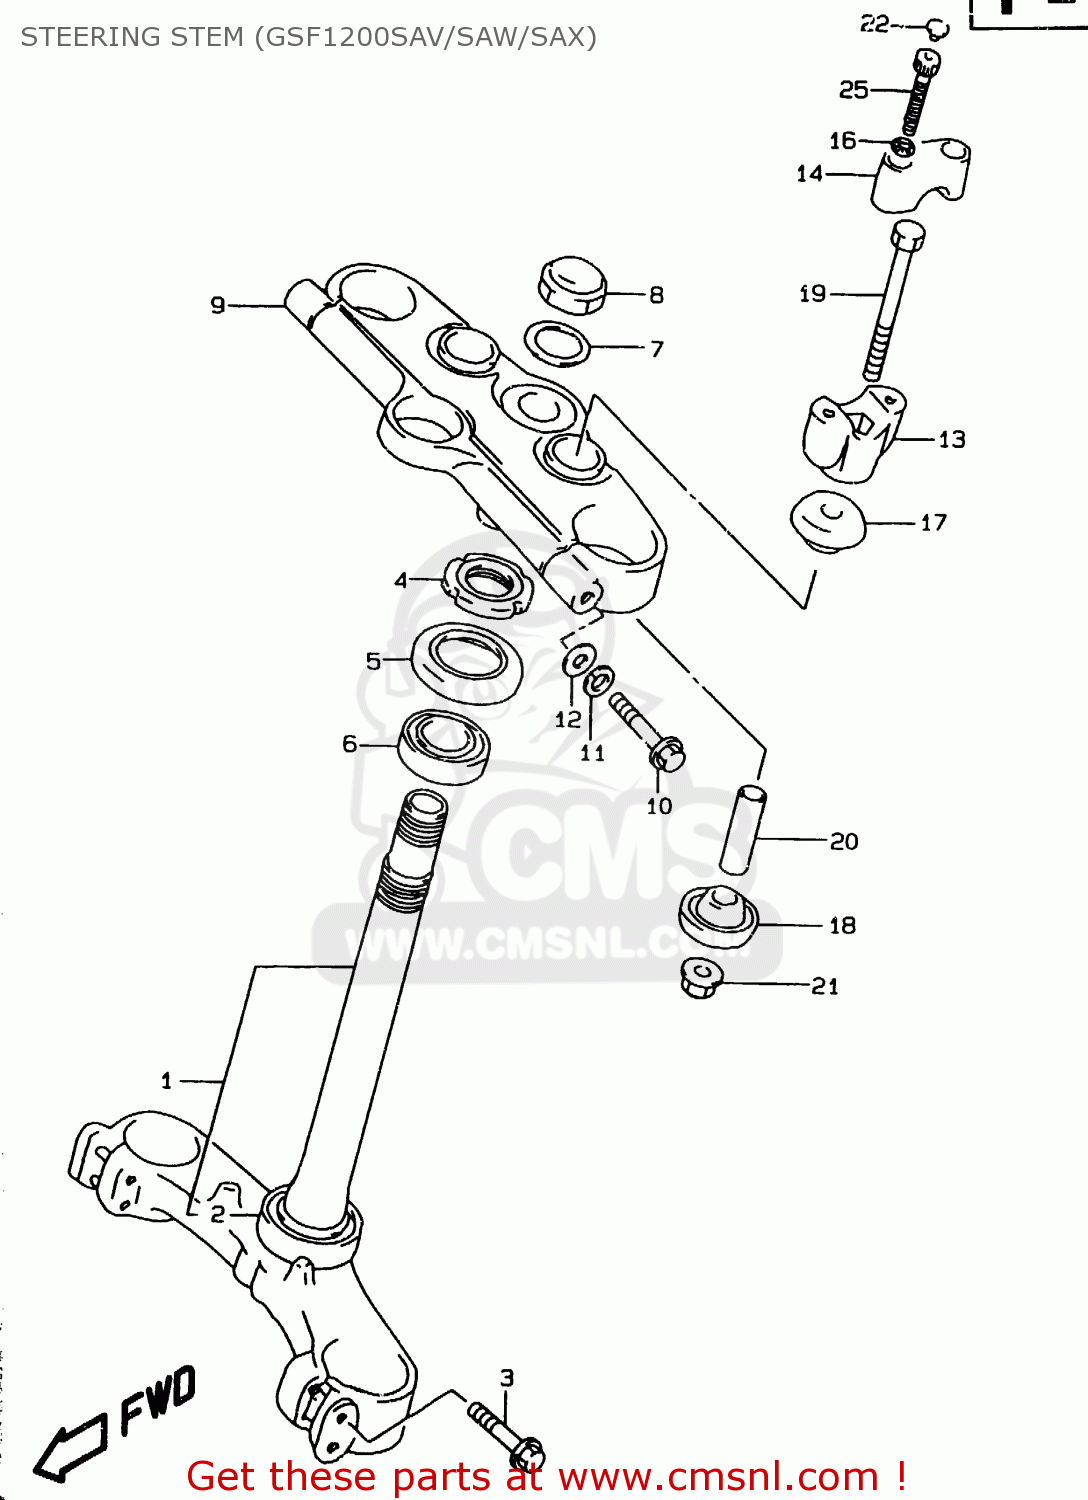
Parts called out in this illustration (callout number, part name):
1	STEM,STEERING
2	BEARING(30X55X17)
3	BOLT
4	NUT,STEERING STEM(25X44X10)
5	SEAL,STEERING UPR DUST
6	BEARING(25X47X15)
7	WASHER(22.5X32X1.6)
8	NUT,CAP
9	HEAD,STEERING STEM
10	BOLT
11	WASHER,LOCK
12	WASHER
13	HOLDER,HANDLE UNDER
14	HOLDER,HANDLE UPR
15	BOLT
16	WASHER
17	CUSHION,RUBBER UPR
18	CUSHION,RUBBER UNDER
19	BOLT,HANDLE HOLDER(10X70)
20	SPACER
21	NUT
22	CAP(OD:11)
